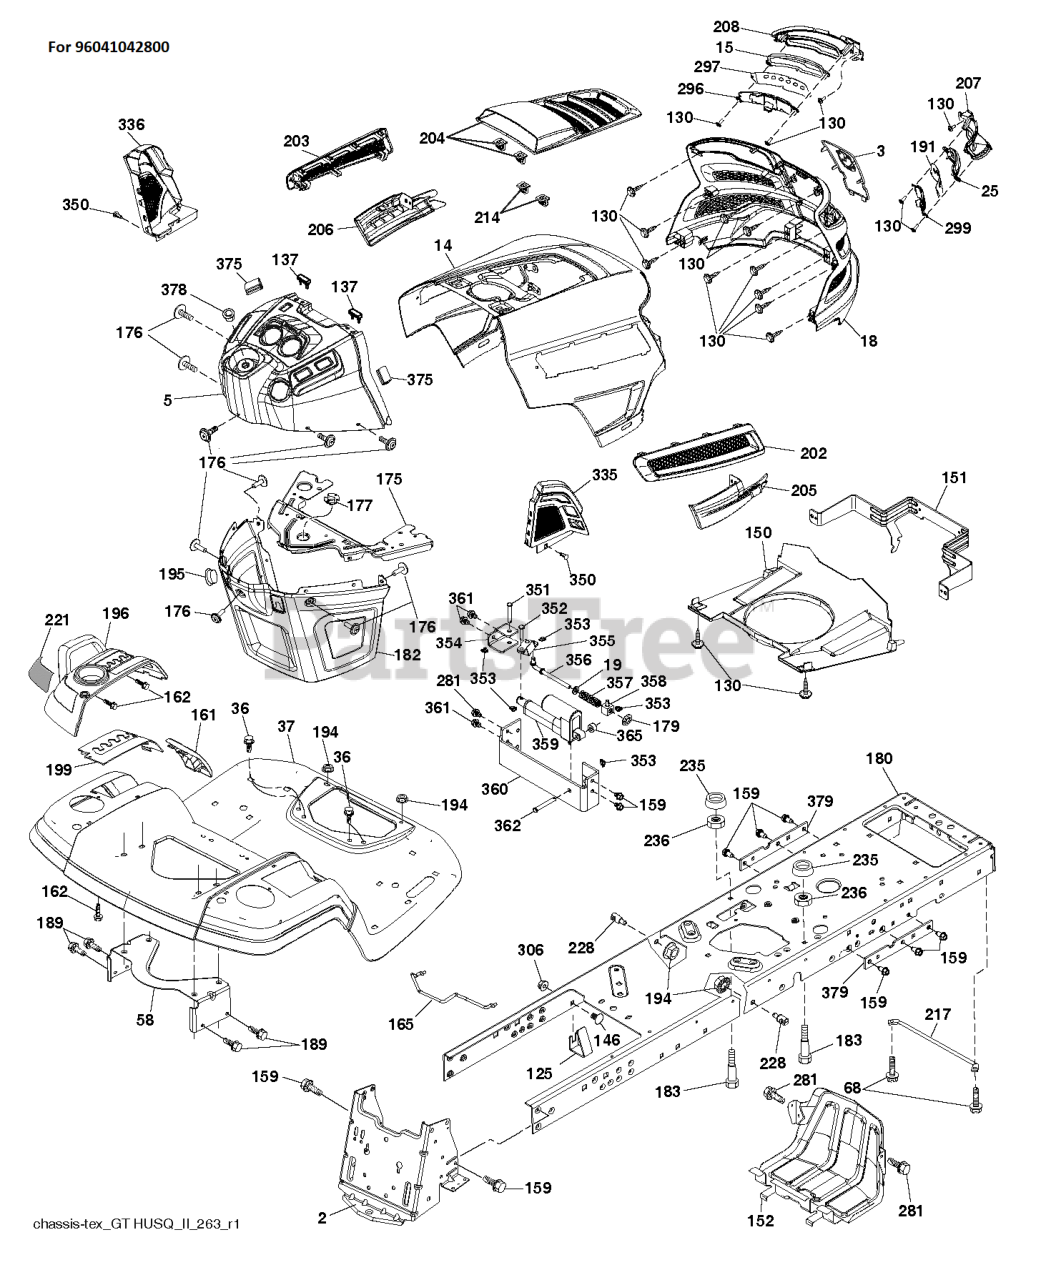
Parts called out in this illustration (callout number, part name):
2	DRAWBAR.STGT
3	APPLIQUE.SUBASM.GT.HUSQ.II
5	DASH.UPR.GT2.DUAL.RD.PTO.MC
14	HOOD.ASM.HUSQVARNA.GT.TEX.ORAN
15	LED LIGHT.LH
25	LENS.RH
36	SCREW 5/16"
37	FENDER.PNT.TX.GT.CH/FW/DL.HUSQ
58	BRKT.SUPPORT.FNDR/TANK
125	CLIP.FUEL.LINE
137	BUMPER DASH
146	BOLT.RDHD.SHT.SQNK.3/8-16X5/8
150	AIR.DUCT.GTV.BLACK
151	BRACKET.PIVOT.HOOD.GT.HUSQ.II
152	SHIELD.BROWNING.PNT.GT.V2
159	SCREW, 3/8-16X3/4
161	CONSOLE.WINDOW.FUEL.HUSQ.GT
165	SUPPORT.TANK.REAR.B/TE
175	PLATE.PNT.CROSSMEMBER.HUSQ/PRE
176	SCREW.#10-24X5/8.RN.QU
177	BUSHING STEERING
180	CHASSIS LTGT BOLTED PAINTED X4
182	DASH.LOWER.COMMON.12V.ADAPTOR
189	SCREW
191	INSERT INFLECT.RH
195	PLUG.HOLE.DASH.LOWER.12V.BLK
196	SUBASM.CONSOLE.HUSQ.GT.DECKLFT
199	PLATE.DECK.LIFT.HUSQVARNA.GT
202	VENT.SIDE.RH.GT.HUSQ.II.
203	VENT.SIDE.LH.GT.HUSQ.II.498
204	VENT.TOP.ASM.HUSQ.GT2
205	SIDE.TRIM.RH.GT.HUSQ.II
206	SIDE.TRIM.LH.GT.HUSQ.II.GRAY
207	BEZEL GT2 LED RH W/ LOWER.ATT
208	BEZEL GT2 LED LH W/ LOWER ATT
214	CLIP.RETAINER.TINNER.
217	ROD.PIVOT.HOOD
221	REFLECTOR.LH.TEX GT HU
228	STUD.W/"D"ANTI-ROTATION
236	NUT.CENTERLOCK.5/16-
281	SCREW 3/8-16X1
296	LED LIGHT.LH
297	INSERT REFECT LH
299	LED LIGHT.RH
306	NUT LOCK FLG 3/8-16 UNC
335	COVER.LOWER.DASH.RH.BLACK
336	COVER-LH.LOWER.DASH.GT2.BLACK
350	CLIP.X-MAS.TREE
351	PIN.CLEVIS.375X2.125
352	PIN.CLEVIS.(.375 X 1.25)
353	CLIP RETAINER
354	SUPPORT.DIFF.LOCK.BELLCRANK.
355	BELLCRANK.PIVOT.LOCK.DIFF
356	LINK.LOCK.DIFF
357	SPRING.COMPRESSION
358	SWIVEL.GUIDE
359	ACTUATOR.ELECTRIC
360	BRACKET.ACUATOR
362	PIN.CLEVIS.(.375 X 2.42)
365	SPACER.NYLON.75" X .4375
375	BUMPER CLIP-ON. DASH 1"
378	BUSHING FLANGE; PLASTIC
379	CHASSIS.PLATE.REINFORCEMNT.431
